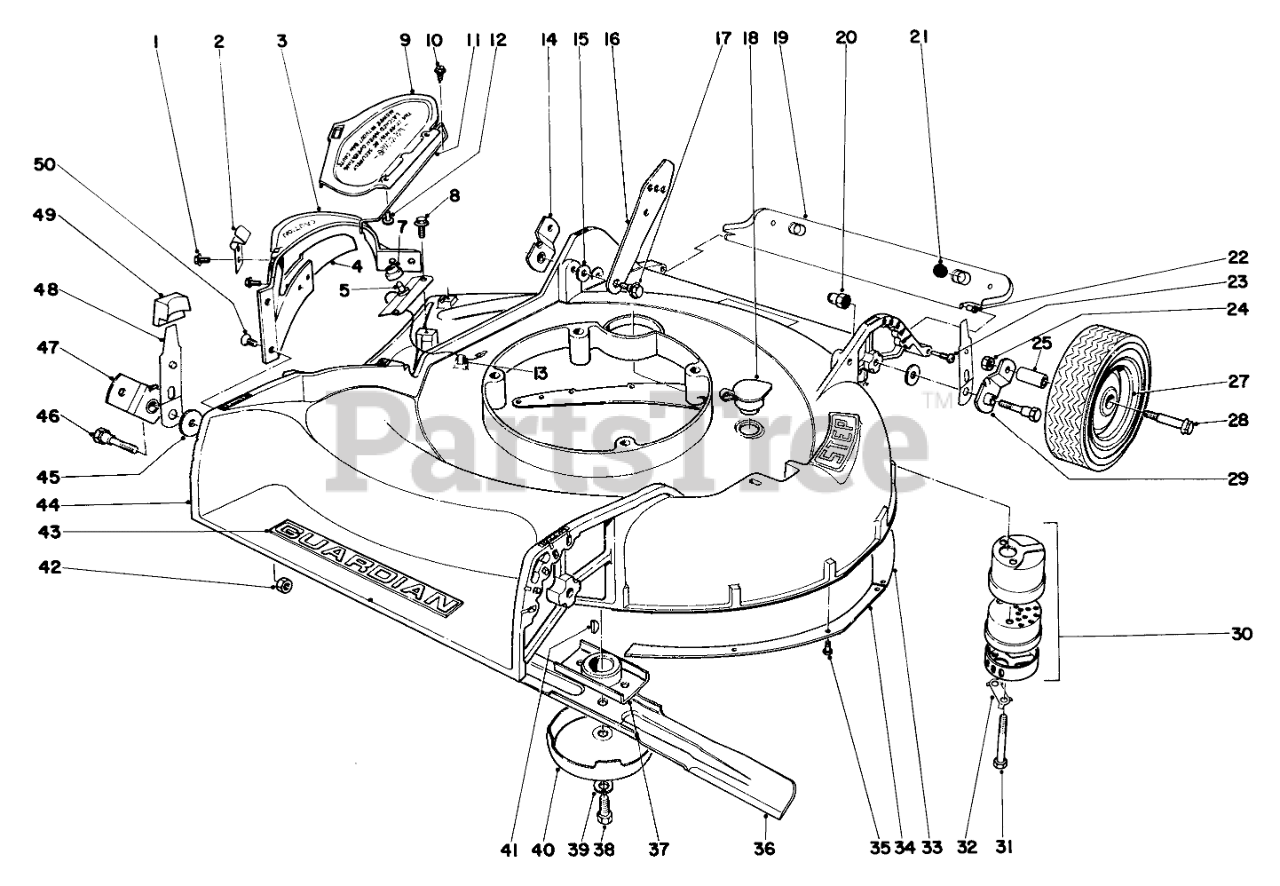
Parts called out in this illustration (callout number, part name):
2	Latch
3	Deflector (Incl. Ref. Nos.1-4)
4	DefIector Bar
5	Deflector Switch & Wire (Incl. Ref. No. 7)
7	Boot Switch
9	Deflector Cover (Incl. Ref. Nos. 11 & 12)
10	SCREW
11	Hinge Pin
12	Rivet
14	Pivot Arm
15	SPACER
16	Handle Latch
17	SCREW-SHOULDER
18	WASHOUT PLUG
19	Rear Safety Shield (Incl. Ref. Nos. 21 & 22)
20	HANDLE PIVOT NUT
21	SKID BUTTON
22	SAFTEY SHIELD BUSHING
23	SAFTEY SHIELD SCREW
24	Nut
25	Bushing
28	Wheel Assembly (Incl. Ref. No. 25)
29	Pivot Arm
30	Muffler (Incl. Ref. Nos. 31 & 32)
31	SCREW-HH
32	CLIP - LOCKING
33	Main Skirt
34	Secondary Skirt
36	Blade
37	BLADE RETAINER WA
38	SPECIAL SCREW
39	WASHER-LOCK
40	AntiScalp Cup
41	KEY-WOODRUFF
42	Nut
43	Emblem
44	Housing (Incl. Ref. Nos. 33, 34, & 35)
45	WASHER-PIVOT
46	5/16-18 PIVOT SCREW
47	Pivot Arm
48	Spring Arm
49	Knob
50	Screw
